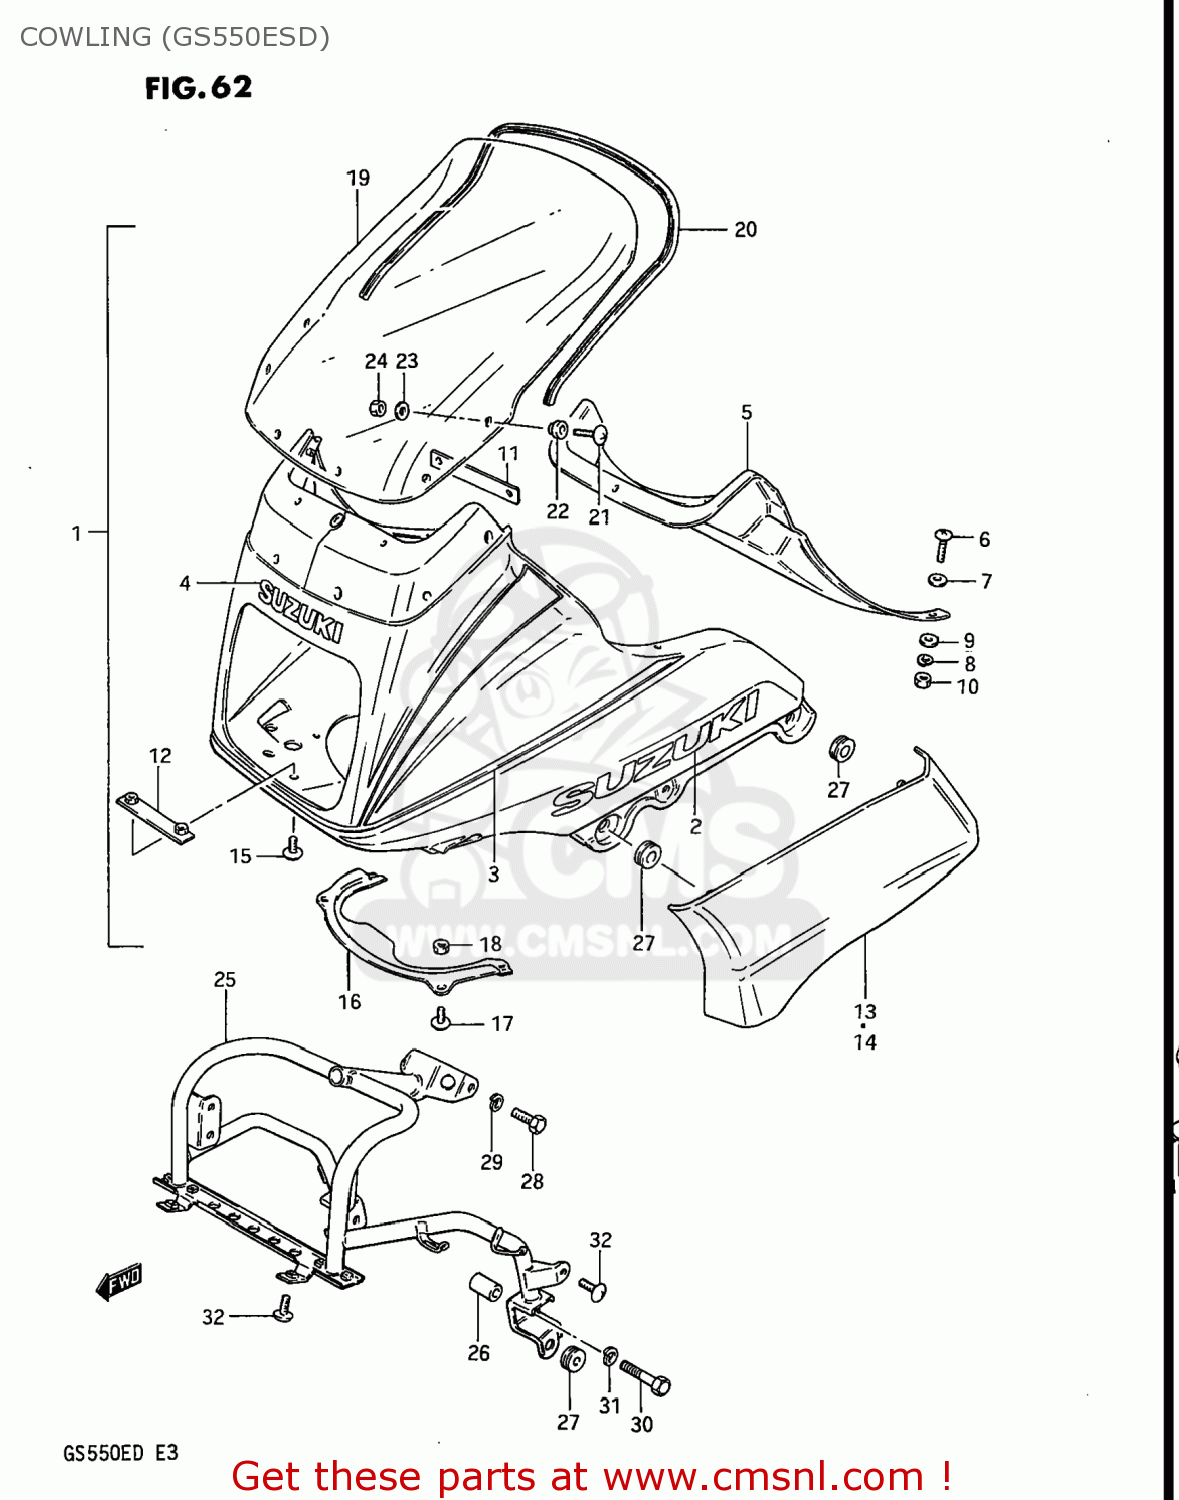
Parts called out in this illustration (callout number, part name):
1	COWLING ASSEMBLY
2	EMBLEM,SUZUKI(BLACK)
3	TAPE SET,COWLING
4	EMBLEM,HEADLAMP
5	PANEL,COWLING,UPPER
6	SCREW
7	WASHER,5MM
8	WASHER,LOCK
9	WASHER,5MM
10	NUT
11	BRACKET,COWLING,UPPER
12	BRACKET,COWLING,LOWER
13	SCREW
14	COVER, LOWER
15	SCREW
16	NUT 5MM
17	WINDOW,COWLING
18	MOLDING,LOWER
19	SCREW
20	CUSHION
21	COVER,COWLING,RIGHT
22	COVER,COWLING,LEFT
23	BRACE,COWLING
24	SPACER (8.2X12.5X23.5)
25	CUSHION
26	BOLT
27	LOCK WASHER
28	BOLT 8X45
29	LOCK WASHER
30	SCREW 6X12
